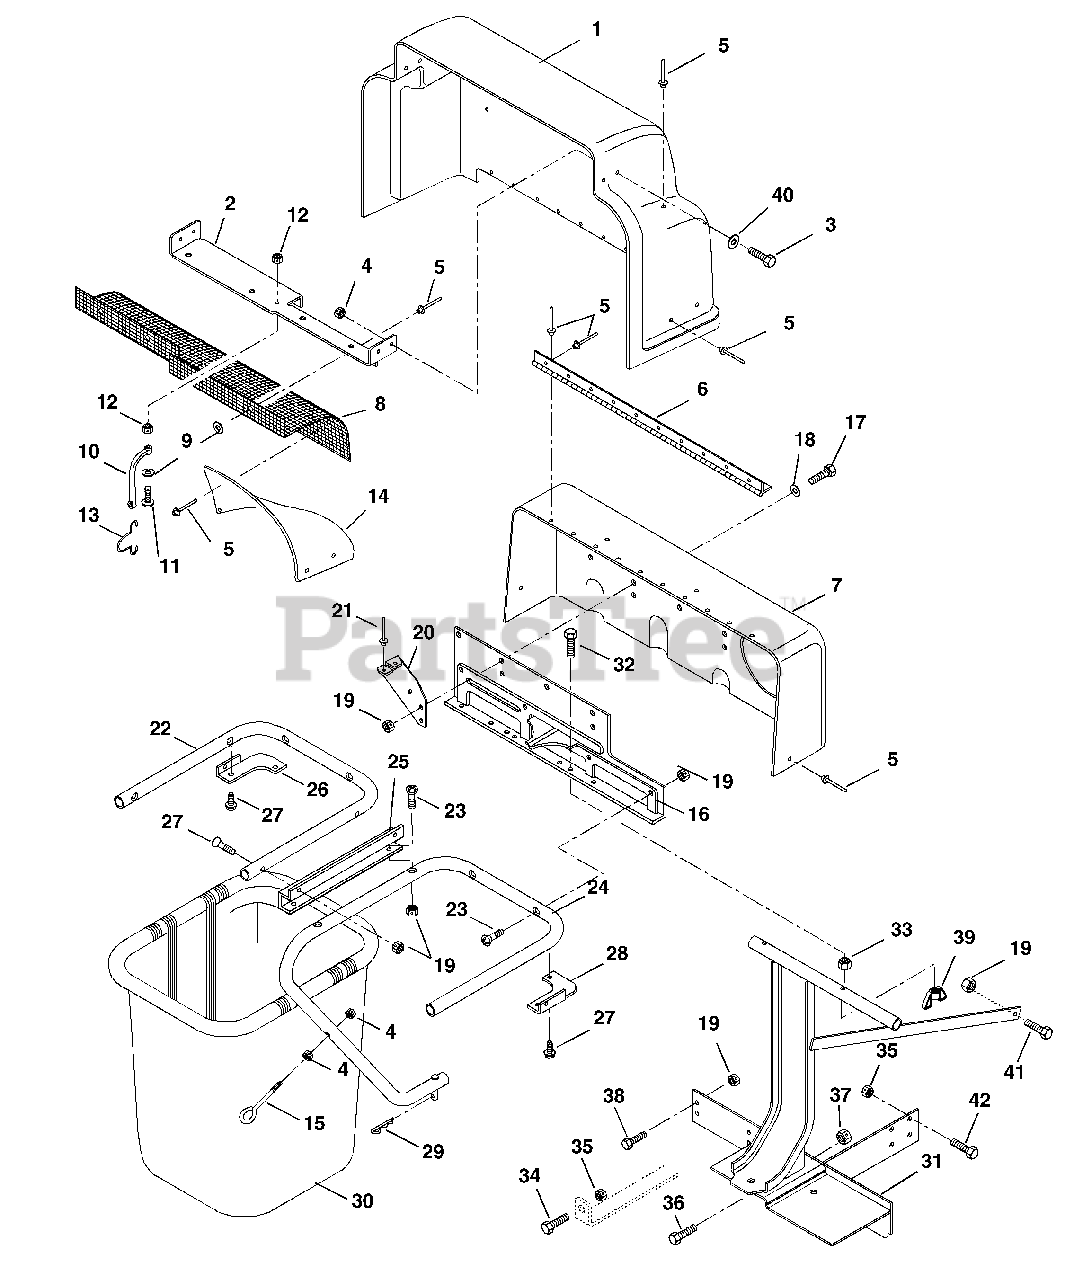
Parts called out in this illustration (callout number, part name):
1	HINGED COVER W/DECALS
2	COVER BRACKET
3	@BLT-HEX .25-20X.50 GR5 YWZC
4	@NUT-LK-CTR .25-20 YWZC
5	RVT-POP .187X.402 DOME ST
7	STATIONARY COVER
9	@WSHR-FL-STL.219X.50X.049 YWZC
10	BATTERY STRAP
11	SCR-MCH 10-24X.88 SLRH YWZC
12	@NUT-LK-NYL 10-24 W/INSRT YWZC
15	EYEBOLT
16	MOUNTING BRACKET
17	BOLT-HEX.31-18X.875 YWZC GR5
18	WSHR-FL-STL .328X.875X.062YWZC
19	@NUT-LK-CTR .31-18 YWZC
21	RVT-POP.187X.527 DOME ST
22	CENTER TUBE
23	SCR-MCH .31-18 X 1.50 YWZC
24	RIGHT TUBE
25	TUBE BRACKET
26	LH CORNER BRACKET
27	@SCR-TAP .31-18X.50 HWH TR YWZ
28	RH CORNER BRACKET
29	PIN-HAIR INT .08X.38X1.42 YWZC
30	GRASS BAGGER BASKET
31	FRAME, BAGGER
32	BLT-HEX .31-18X1.75 FLTHD YWZC
33	@NUT-HEX .31-18 YWZC
34	@BLT-HEX .38-16X1.25 GR5 YWZC
35	@NUT-LK-CTR .38-16 YWZC
36	@BLT-HEX .50-13X1.00 GR5 YWZC
37	@NUT-LK-CTR .50-13 YWZC
38	@BLT-HEX .31-18X1.00 GR5 YWZC
39	NUT-NYLK WING .312-18 YWZC
40	@WSHR-FL-STL.281X.62X.065 YWZC
41	@BLT-HEX .31-18X1.25 GR5 YWZC
42	@BLT-HEX .38-16X1.00 GR5 YWZC
